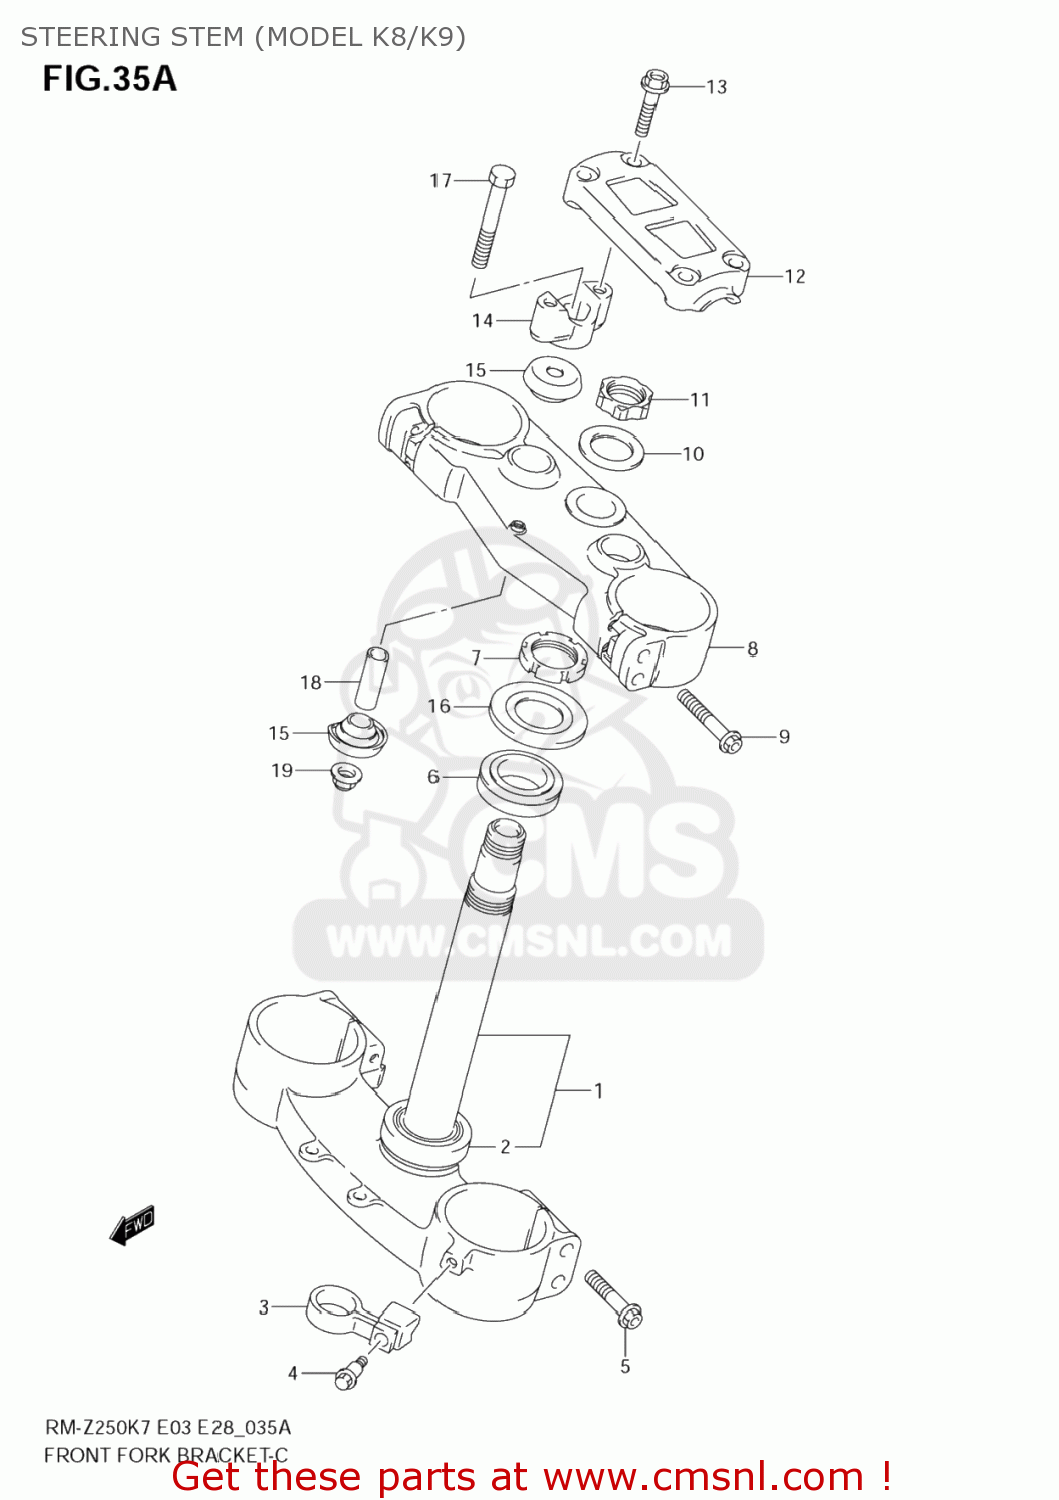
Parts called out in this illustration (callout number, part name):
1	STEM,STEERING
2	BEARING(30X52X16)
3	GUIDE,FR BRAKE HOSE
4	BOLT(6X20.5)
5	BOLT
6	BEARING(30X52X16)
7	NUT,STEERING
8	HEAD,STEERING
9	BOLT
10	WASHER,STEM HEAD
11	NUT,STEM HEAD
12	HOLDER,HANDLE
13	BOLT
14	HOLDER,HANDLE,
15	CUSHION,RUBBER
16	SEAL,STEERING UPR DUST
17	BOLT
18	SPACER
19	NUT
